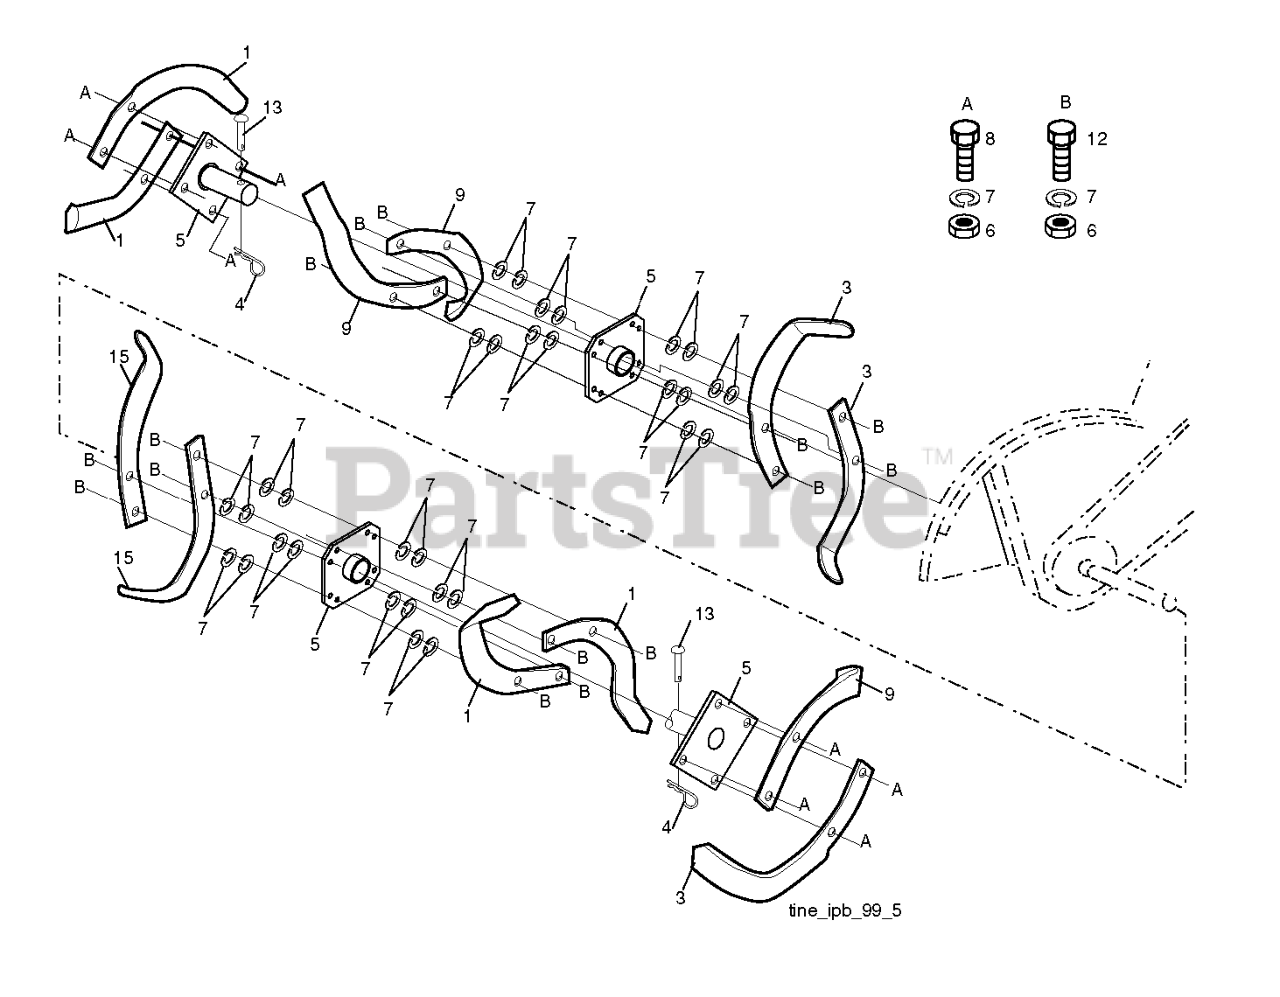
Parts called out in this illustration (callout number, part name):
1	TINE, LH 14"
3	TINE.LH.14".CRT
4	SPRING RETAINER
5	TINE.HUB.ASM.W/SHEILD
6	NUT
7	WASHER, LOCK 3/8
8	BOLT.HEX.001X20.37-24X1.ZINC
9	TINE, RH 14"
12	BOLT.3/8-24X1-1/2
15	TINE.RH.14".CRT
